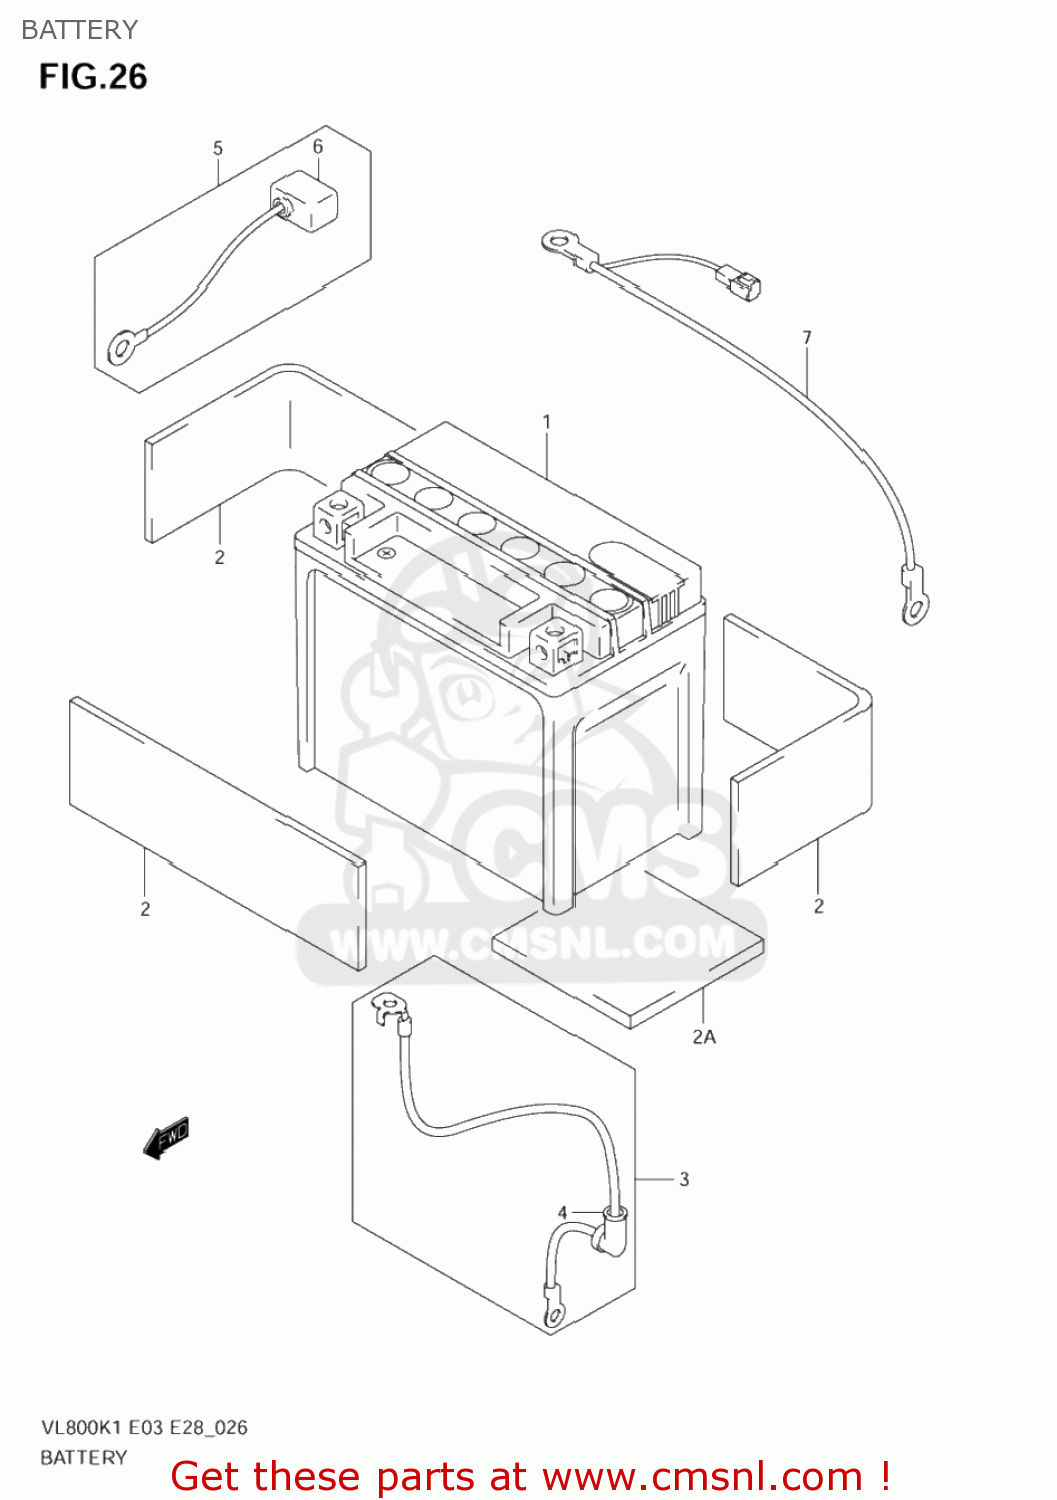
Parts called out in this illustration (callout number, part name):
1	BATTERY ASSEMBLY (12V) FTX
2	PROTECTOR(170X95X3.0)
2A	PROTECTOR(50X50X5)
3	WIRE,STARTER MOTOR LEAD
4	CAP,STARTER MOTOR LEAD
5	WIRE,BATTERY PLUS LEAD
6	CAP,BATTERY PLUS
7	WIRE,BATTERY MINUS
